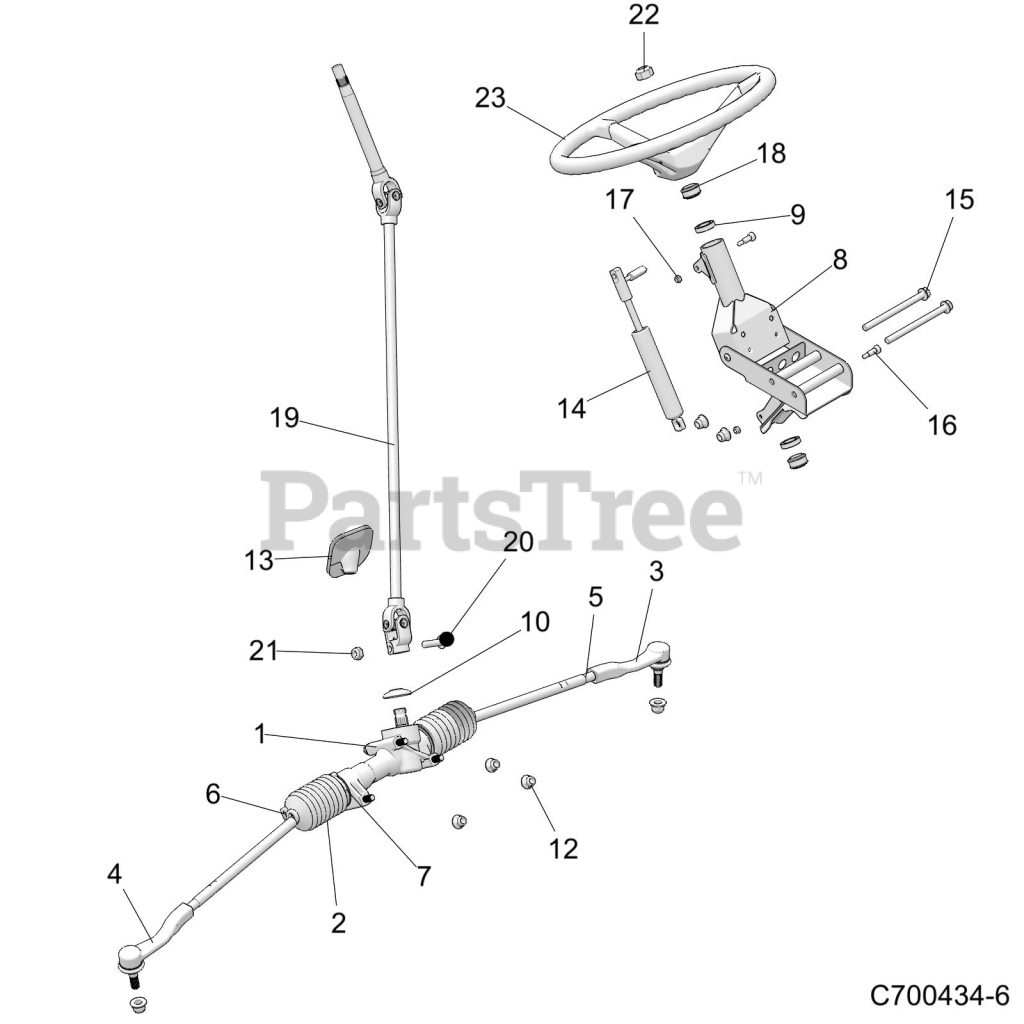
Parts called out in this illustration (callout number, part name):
1	ASM-GEAR BOX,STEERING
2	BOOT-DRIVER SIDE,RACK
3	D.S. OUTER TIE ROD
4	P.S. OUTER TIE ROD
5	NUT, JAM
6	CLAMP, SMALL
7	CLAMP, LARGE
8	ASM,TILT,STEERING,RVTD,M10.BLK
9	BEARING-STEERING
10	COVER-DUST,STEERING
11	NUT-M8X1.25,FLG,NYLOC-OLIVE D
12	NUT-M10X1.25,FLG,NYLOC-OLIVE D
13	GROMMET-STEERING
14	ASM-SHOCK,OIL LOCKING,MACH
15	BOLT-M10X1.25X130,HXFLG-OLIVED
16	BOLT-SHOULDER,M8-15,M6X1.0-BLK
17	NUT,NYLOK(10)
18	BUSHING-STEERING
19	SHAFT-STEERING,UPPER/LOWER
20	SCR-M10X1.50X35 HX/FL
21	NUT-NY INS,M10X1.5,HEX,ZINC,YW
22	NUT-HEX-M16X2, 8 ZC NYL
23	WHEEL-STEERING,15"
